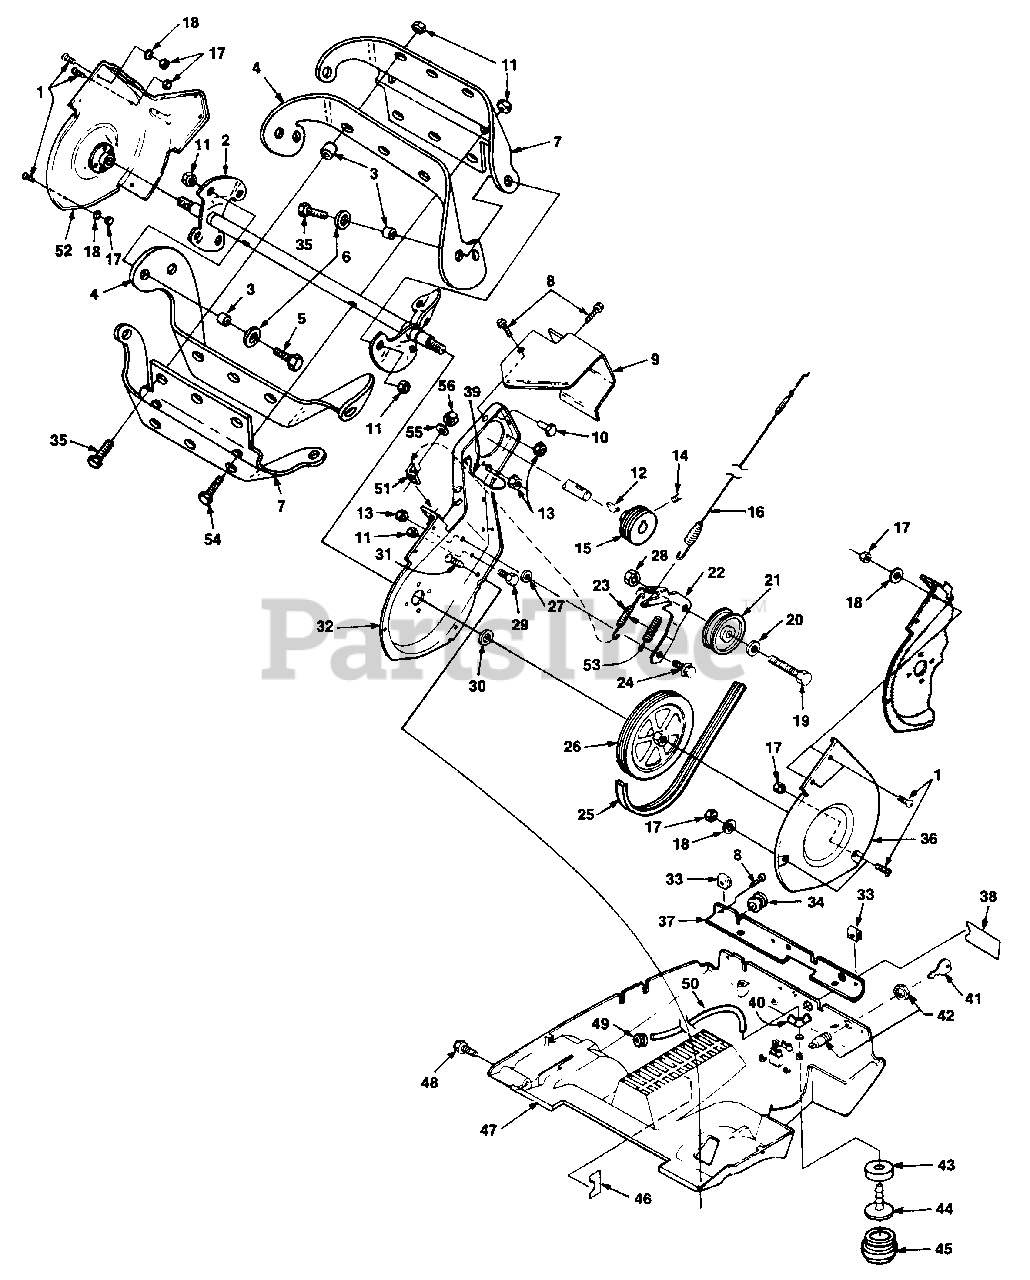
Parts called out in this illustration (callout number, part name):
1	SCREW- Phillips #10-24 x 5/8
2	SHAFT- Auger
4	BLADE- Auger (set of 2)
5	SCREW- Hex 1/4-20 x 3/4
6	WASHER- Plain 1/4
7	CLAMP- Plate
9	SHIELD- Belt
10	NUT- Flange
11	NUT- Flange 1/4-20
12	KEY- 5/8 x 5/32
13	NUT- Flange 5/16-18
14	SCREW- Set
15	PULLEY- Drive
16	CABLE & SPRING
17	NUT-#10-24
18	WASHER- Retaining
19	SCREW- Hex hd. 3/8-16 x 1 1/2
20	WASHER- Flat 3/8
22	ARM- Idler
23	SPRING- Extension
25	BELT- Drive
26	PULLEY- Driven
28	NUT
29	SCREW- 1/4-20 x 5/8
31	SCREW- Plastite 1/4-20 x 5/8"
32	FRAME- Left side
33	NUT- Speed
34	GROMMET- Metal
35	SCREW- Hex 1/4-20 x 7/8
36	GUARD- Belt
37	PANEL- Bracket control
38	DECAL- Electric start
39	GUIDE- Belt
40	NUT- Wing 1/4-20
41	KEY (set of 2)
42	SWITCH
43	CUP- Fuel primer
44	FITTING- Fuel primer
45	BULB- Fuel primer
46	DECAL- Fuel valve
47	COWLING- Lower
48	SCREW- 1/4-20 x 5/8
50	TUBE- Rubber (cut to 15 3/4)
51	CLIP- Spring
52	FRAME- Right side
53	COVER- Spring
54	SCREW- Hex hd. 1/4-20 x 1 1/4"
55	WASHER- Lock 1/4
56	NUT- Hex 1/4-20
